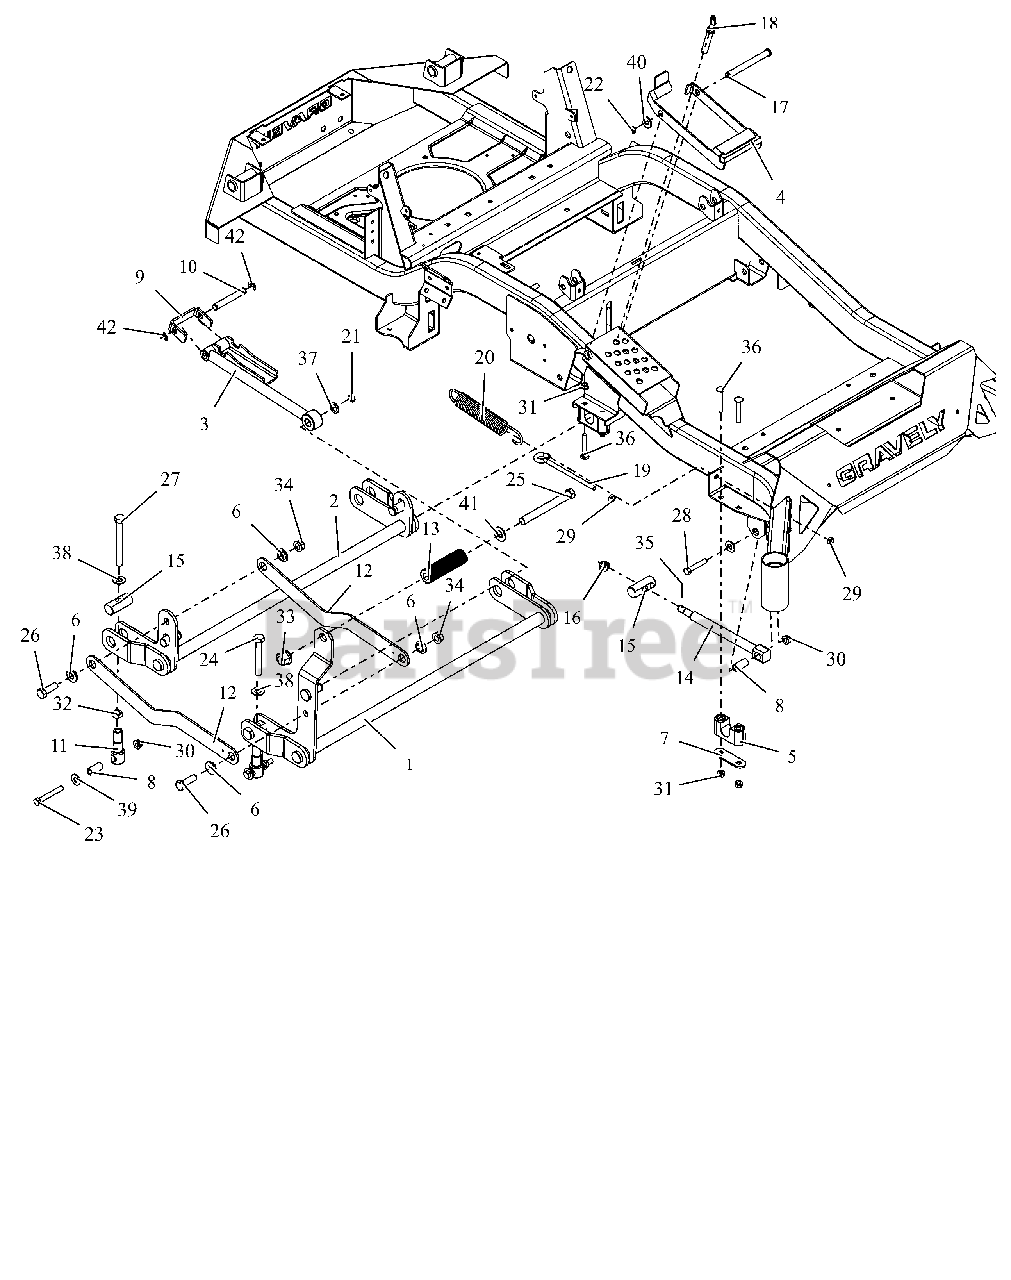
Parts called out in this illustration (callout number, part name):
1	WLDMT, FRONT DECK LIFT PIVOT
2	WLDMT, REAR DECK LIFT PIVOT
3	WLDMT, HOC ARM
4	BRKT, HOC TRANSFER LOCK
5	ASM-BUSHING, DECK LIFT
6	BSHG-FLG .515X.750X.310X1.120
7	PLATE, BEARING SUPPORT
8	SPACER, DECK LEVELING
9	BRKT, HOC LINE
10	ROD, HOC PIVOT
11	LINK, DECK LIFT FORMED
12	LINK, DECK LIFT
13	ROD, FOOT PEDAL (BLACK)
14	DRAG,LINK-HD
15	PIN, DECK LIFT
16	NUT-SL .50-13
17	PIN-CLEV .50X4.75X4.55
18	PIN, .50 X 2.20 USABLE LG BALL
19	BOLT,.38-16 X 5.25-.62 DIA EYE
20	SG-TENS .162X1.25X8.25 WLD 25
21	RG-RTNG-EXT .625X.050
22	RG-RTNG-EXT .500X.050 (SNAP)
23	BLT, HEX .38-16X2.75 G8 ZCC
24	BLT, HEX 0.5-13X3.5F GR5 ZCC
25	BLT, HEX .62-11X5.50 G5 FBP
26	BLT,HEX .50-13X1.50 G5 ZCC
27	BLT, HEX .50-13X4.50F G8 ZCC
28	BLT,HEX .38-16X2.00 G5 ZCC
29	NUT-JAM .375-16 G2 ZCC
30	NUT-LK-TOP-FLG .38-16 ZC120
31	NUT,LK-CTR-FLG .31-18 GF ZCC
32	NUT-JAM .500-13 G2 ZCC
33	NUT,FLG-TOP LK .625-11 FBP
34	NUT-LK-TOP-FLG .500-13 GF ZCC
35	PIN,CTR.12X1.25EXTPRSQCT ZC120
36	BLT, RHSSN.31-18X2.25 G5 ZCC
37	WSHR, FLT .630X1.005X.062 ZCC
38	WSHR, FLT .557X1.040X.102 ZCC
39	WSHR,FLT .438X1.00X.083 ZCC
40	WSHR,FLT .531X1.062X.095 ZCC
41	WSHRFLT 5/8SAE CARBHARD FBP
42	RG-RTNG-EXT .500X.042 (E)
